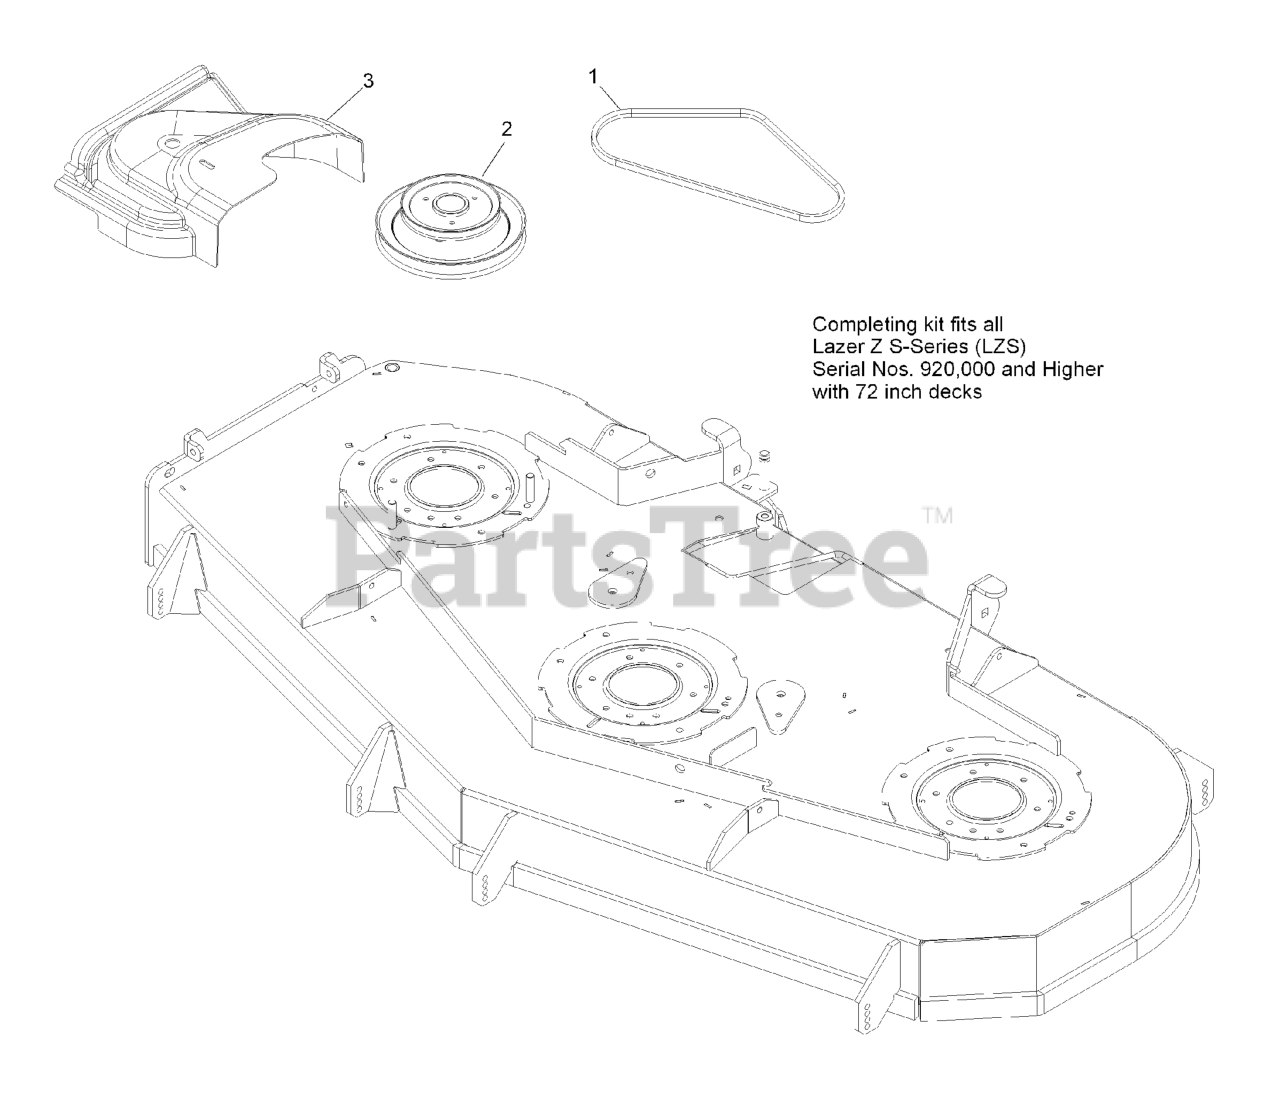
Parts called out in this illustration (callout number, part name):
1	BELT, BLOWER DRIVE 72
2	JACKSHAFT,UV DRIVE 724 SPLINED
3	COVER,BELT UV 72
